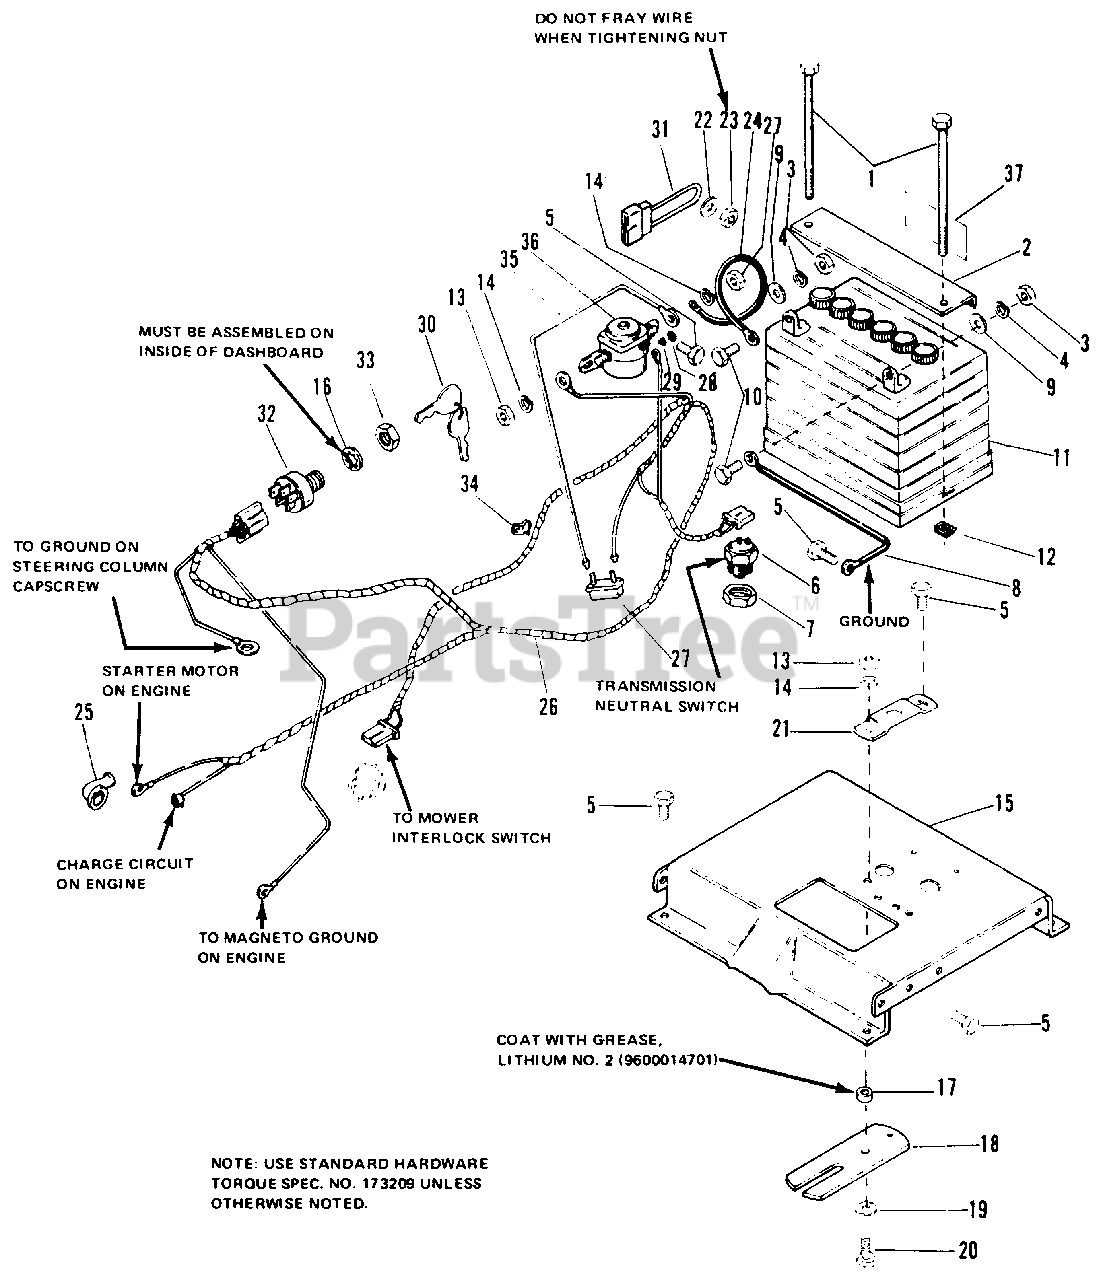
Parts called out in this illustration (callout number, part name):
1	BOLT, 1/4-20 x 7
2	CLAMP, Battery
3	NUT, Hex, 1/4-20
4	LOCKWASHER, 1/4
5	SCREW, Taptite, 1/4-20 x 3/8
6	SWITCH, Interlock
7	NUT, Pal, 9/16-18
8	CABLE, Ground
9	WASHER, Plain, 1/4
10	CAPSCREW, Hex, 1/4-20 x 3/4
12	NUT, Speed, 1/4-20
13	NUT, Hex, 5/16-18
14	LOCKWASHER, 5/16
15	SUPPORT, Frame
16	LOCKWASHER, Internal, 5/8
18	LEVER, Switch
20	CAPSCREW, 5/16-18 x 1
21	BRACKET, Switch
22	WASHER, Cup
23	NUT, Hex, full lock, 5/16-18
25	COVER, Terminal
26	HARNESS, Wire
27	BREAKER, Circuit
28	NUT, Hex, 10-32
29	LOCKWASHER, Ext. No. 10
30	KEYS, Ignition (on ring)
31	WIRE, Mower Bypass
32	SWITCH, Ignition
33	NUT, Hex, special 5/8-32
35	WIRE ASSEMBLY
37	FILM, Battery
